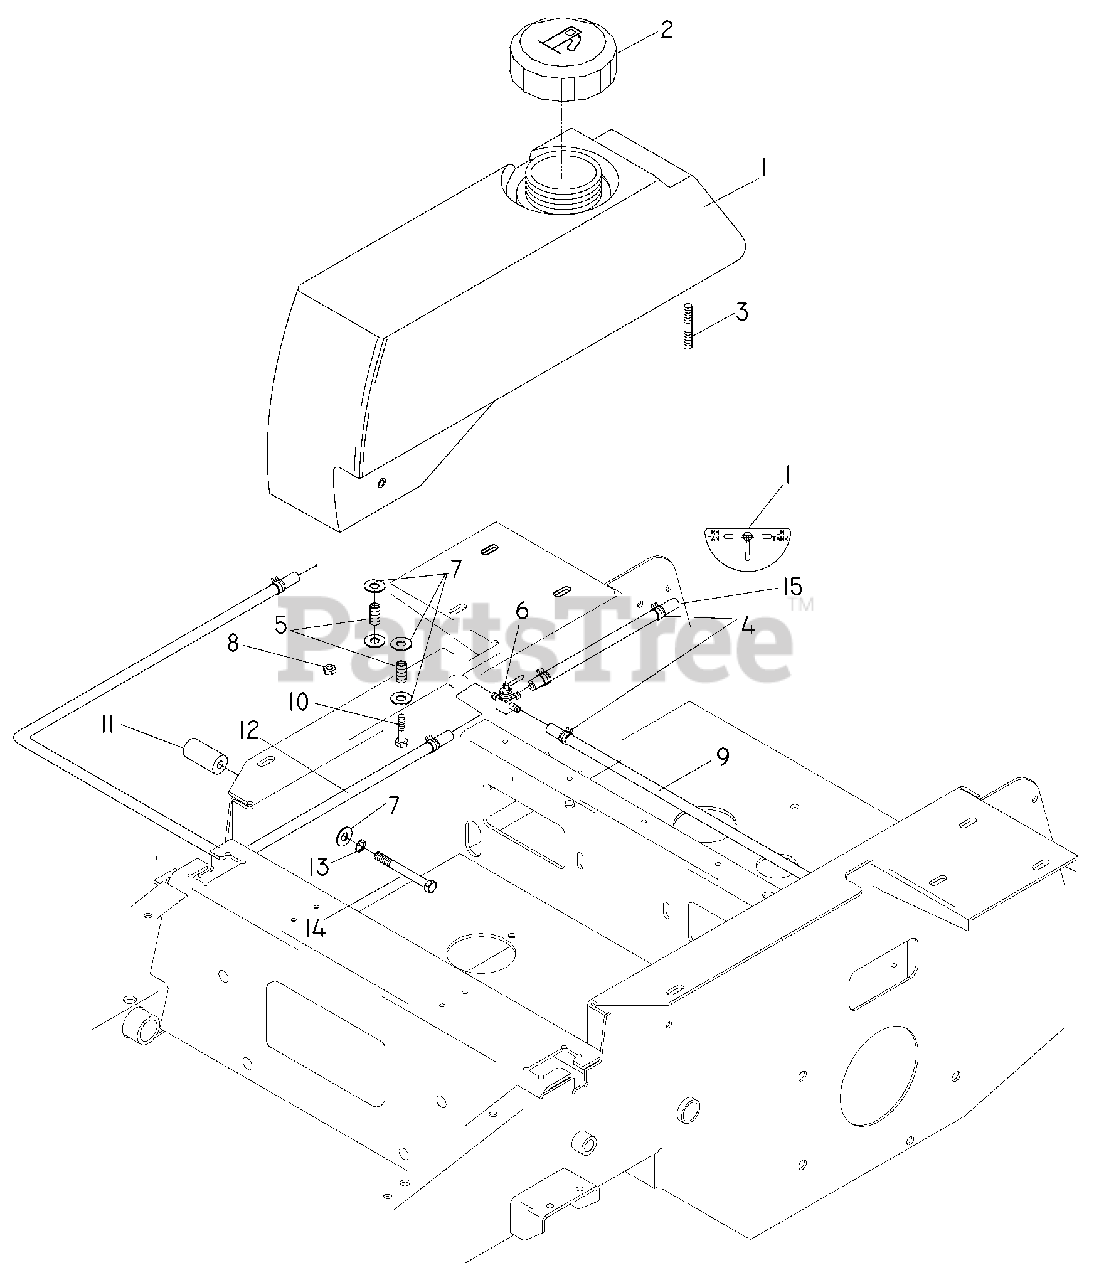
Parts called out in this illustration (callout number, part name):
1	FUEL TANK RT
2	FUEL CAP
4	HOSE CLAMP
6	FUEL VALVE
7	WASHER, 5/16 STD FLT
8	NUT 5/16-18 CENTERLOCK
10	HCS 5/16-18 x 1
11	TANK SPACER
13	WASHER 5/16 LOCK
14	HCS 5/16 X 4.0
16	DECAL, FUEL LINE
